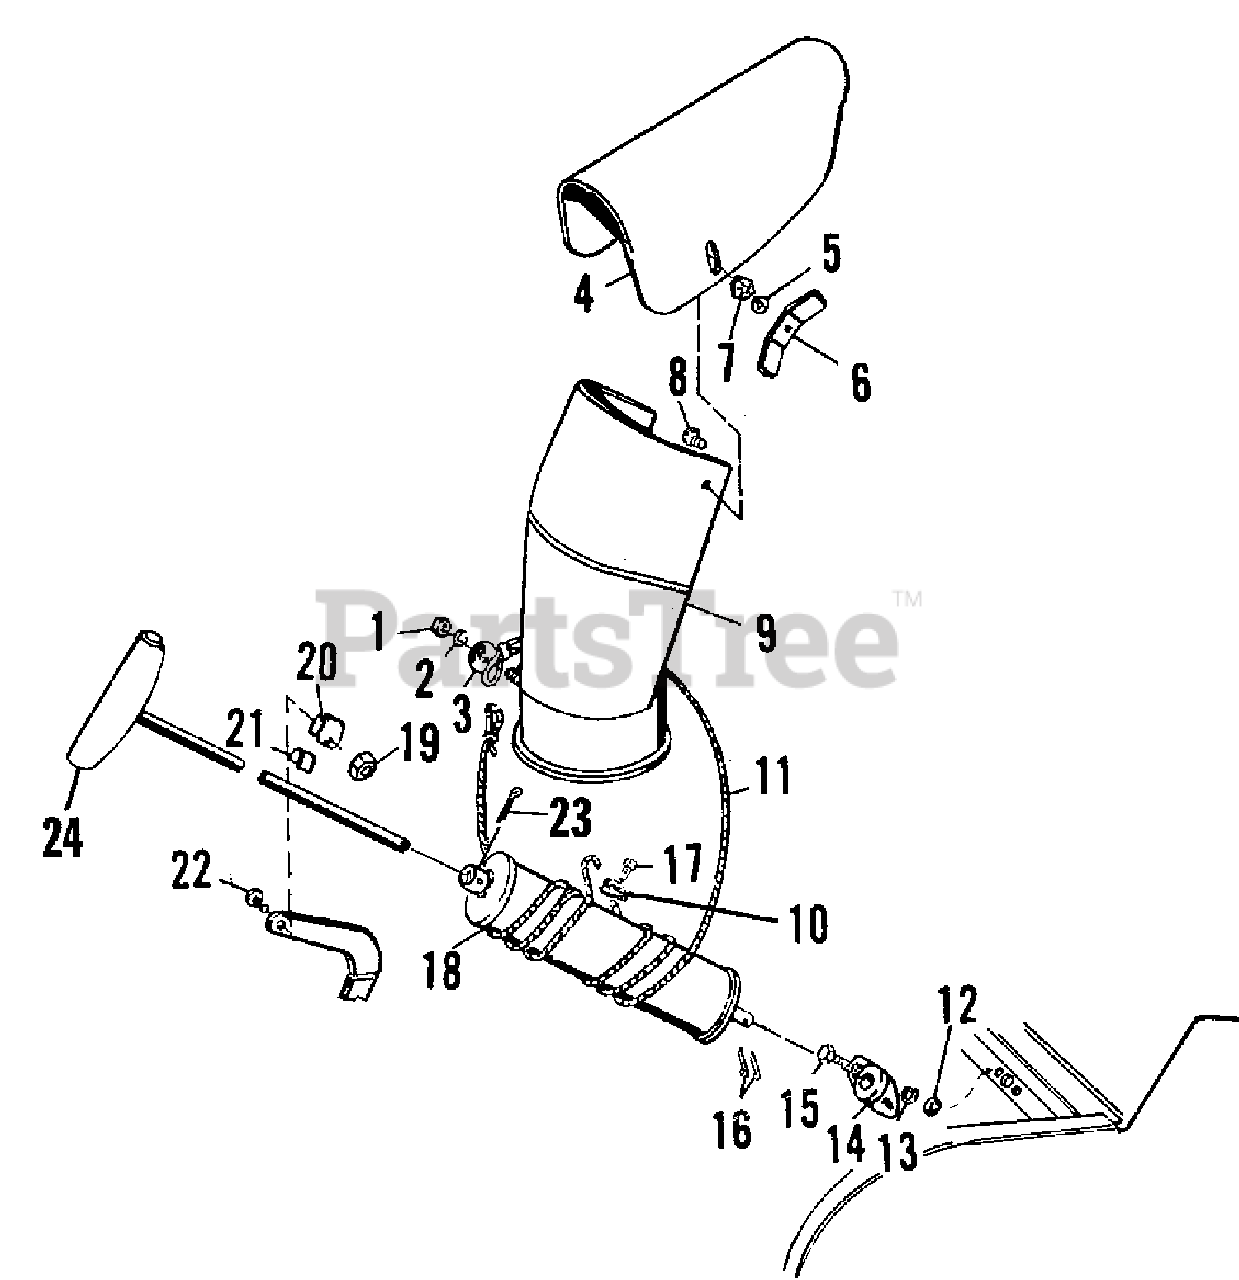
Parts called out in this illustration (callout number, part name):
1	NUT, Hex, 5/16-18
2	WASHER, Lock, 5/16
4	EXTENSION, Spout
5	WASHER, Flat, 3/8
6	NUT, Wing, 5/16-18
7	WASHER, Lock, Shakeproof, 3/8
8	BOLT, Carriage, 5/16-18 x 3/4
10	CLAMP, Cable
12	NUT, Hex, 1/4-20
13	WASHER, Lock, 1/4"
15	SCREW, Hex Cap, 1/4-20 x 5/8
16	PIN, Cotter, 3/32 x 3/4
17	SCREW, Taptite, 1/4-20 x 3/8
18	TUBE, Spout Control
19	NUT, Hex Lock, 5/16-18
21	LINER, Guide
22	SCREW, Hex Cap, 5/16-18 x 1-1/2
23	PIN, Cotter, 5/32 x 1
